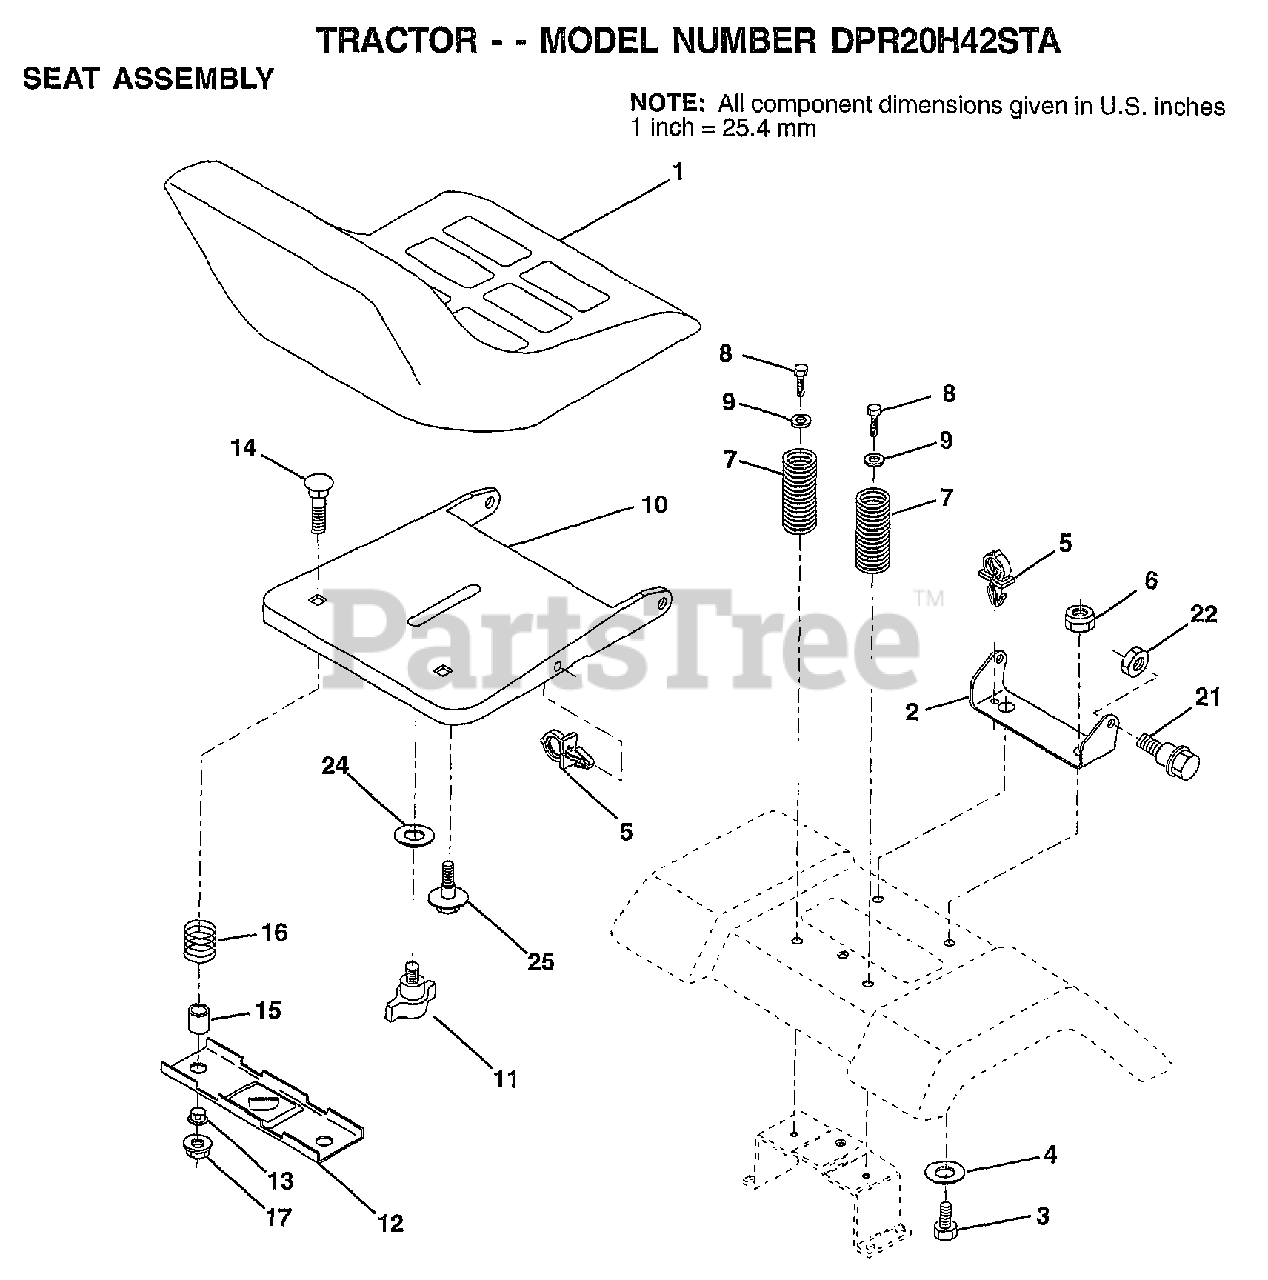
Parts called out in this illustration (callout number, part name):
1	SEAT
2	BRACKET PVT SEAT
3	BOLT
4	WASHER PM
5	CLIP.PUSH-IN.HING
6	NUT
7	SPRING COMPRESSIO
8	SCREW
9	WASHER
10	PAN-SEAT
11	KNOB.SEAT.ADJ.WINGNUT
12	BRKT SWITCH
13	BUSHING
14	BOLT-RD HD SQ NK
15	SPLIT SPACER
16	SPRING
21	BOLT
22	NUT
24	WASHER
25	"BOLT,SHOULDER"
